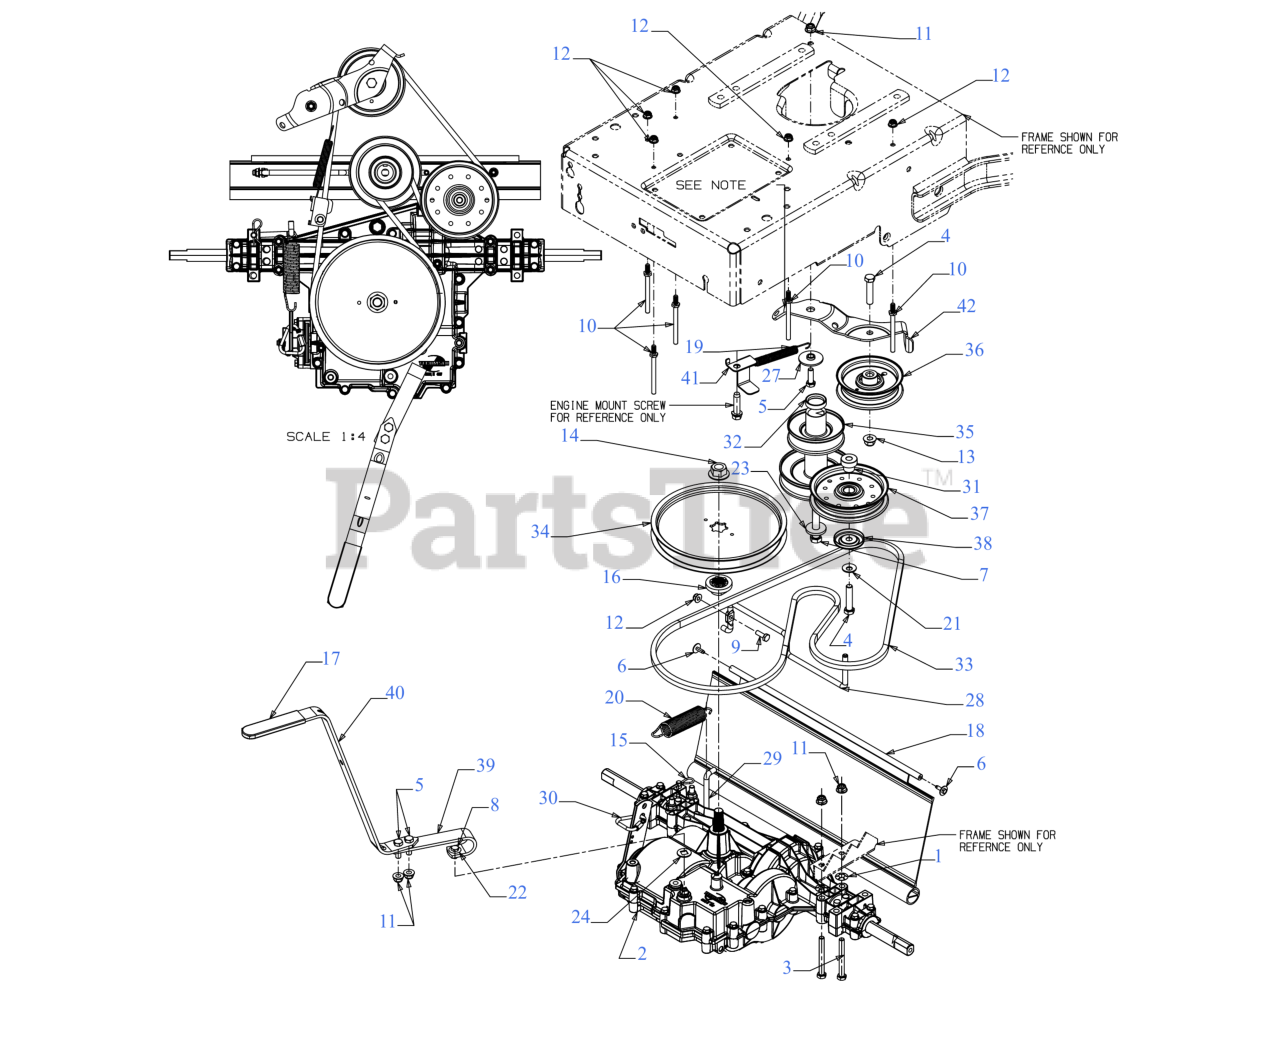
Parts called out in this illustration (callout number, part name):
1	PUSH RETAINER 5/16
2	TRANSAXLE-4 SPEED
3	HEX SCREW 5/16-18 x 2.75
4	HEX SCREW 3/8-16 x 1.75 GR5
5	SCREW 5/16-18 x 1.0 GR5
6	SCREW 10-16 x .625
7	SCREW 7/16-20 x 3.00 GR5
8	BOLT 1/4-28 x .625 GR8
9	SCREW 1/4-20X.75 GR5
10	BELT KEEPER
11	FLANGE LOCK NUT 5/16-18
12	FLANGE LOCK NUT
14	FLANGE NUT W/HUB
15	INTERNAL COTTER PIN
16	PULLEY HUB
18	WIDECUT TRAILSHIELD
19	EXTENSION SPRING WHEEL DRIVE
20	EXTENSION SPRING
21	BELL WASHER .400 ID x .88 x .060
22	SPRING WASHER BELL
23	FLAT WASHER .445 x 1.248 x .170
24	FLAT WASHER .390X.870X.060
27	SHOULDER SPACER
28	BELT KEEPER ROD
29	BRAKE ROD SPRING MOUNT
30	TRI LINK COUPLING
31	SHOULDER SPACER
32	SPACER
33	V-BELT 4L x 64.2
34	TRANSMISSION PULLEY
35	ENGINE PULLEY
36	IDLER PULLEY
37	IDLER PULLEY 4.25 DIA
38	IDLER PULLEY CAP
